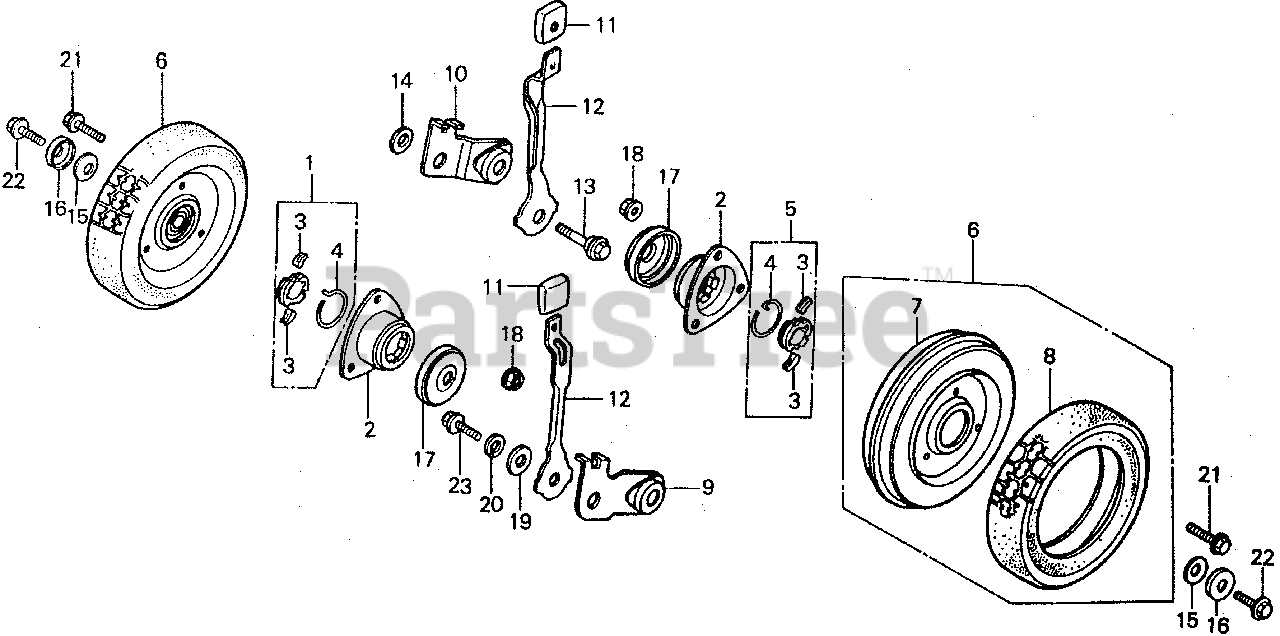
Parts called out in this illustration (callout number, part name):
1	HOLDER, R. RATCHET
2	RECEIVER, RATCHET
4	SPRING, RATCHET RETURN
5	HOLDER, L. RATCHET
6	WHEEL (NA USE ALT:06427-960-305)
7	WHEEL, RR. (NOT AVAILABLE)
8	TIRE (8X1.57)
9	ARM, R. RR. ADJUSTING (NOT AVAILABLE)
10	ARM, L. RR. ADJUSTING (NOT AVAILABLE)
11	GRIP, ADJUSTER
12	PLATE, RR. ADJUSTING
13	BOLT, RR. ADJUSTING ARM
14	WASHER (10MM) (NOT AVAILABLE)
15	WASHER, SPRING
16	WASHER, HANDLE CUSHION
17	DUST SEAL (NOT AVAILABLE)
18	NUT, FLANGE (6MM)
19	WASHER, PLAIN (8MM)
20	WASHER, SPRING (8MM)
21	BOLT, FLANGE (6X12) Use up to Engine SN 1543277.
22	BOLT, FLANGE (8X12)
23	BOLT, FLANGE (8X16) Use up to Frame SN 1008045.
23	BOLT, FLANGE (8X16) Use from Engine SN 1000016.
